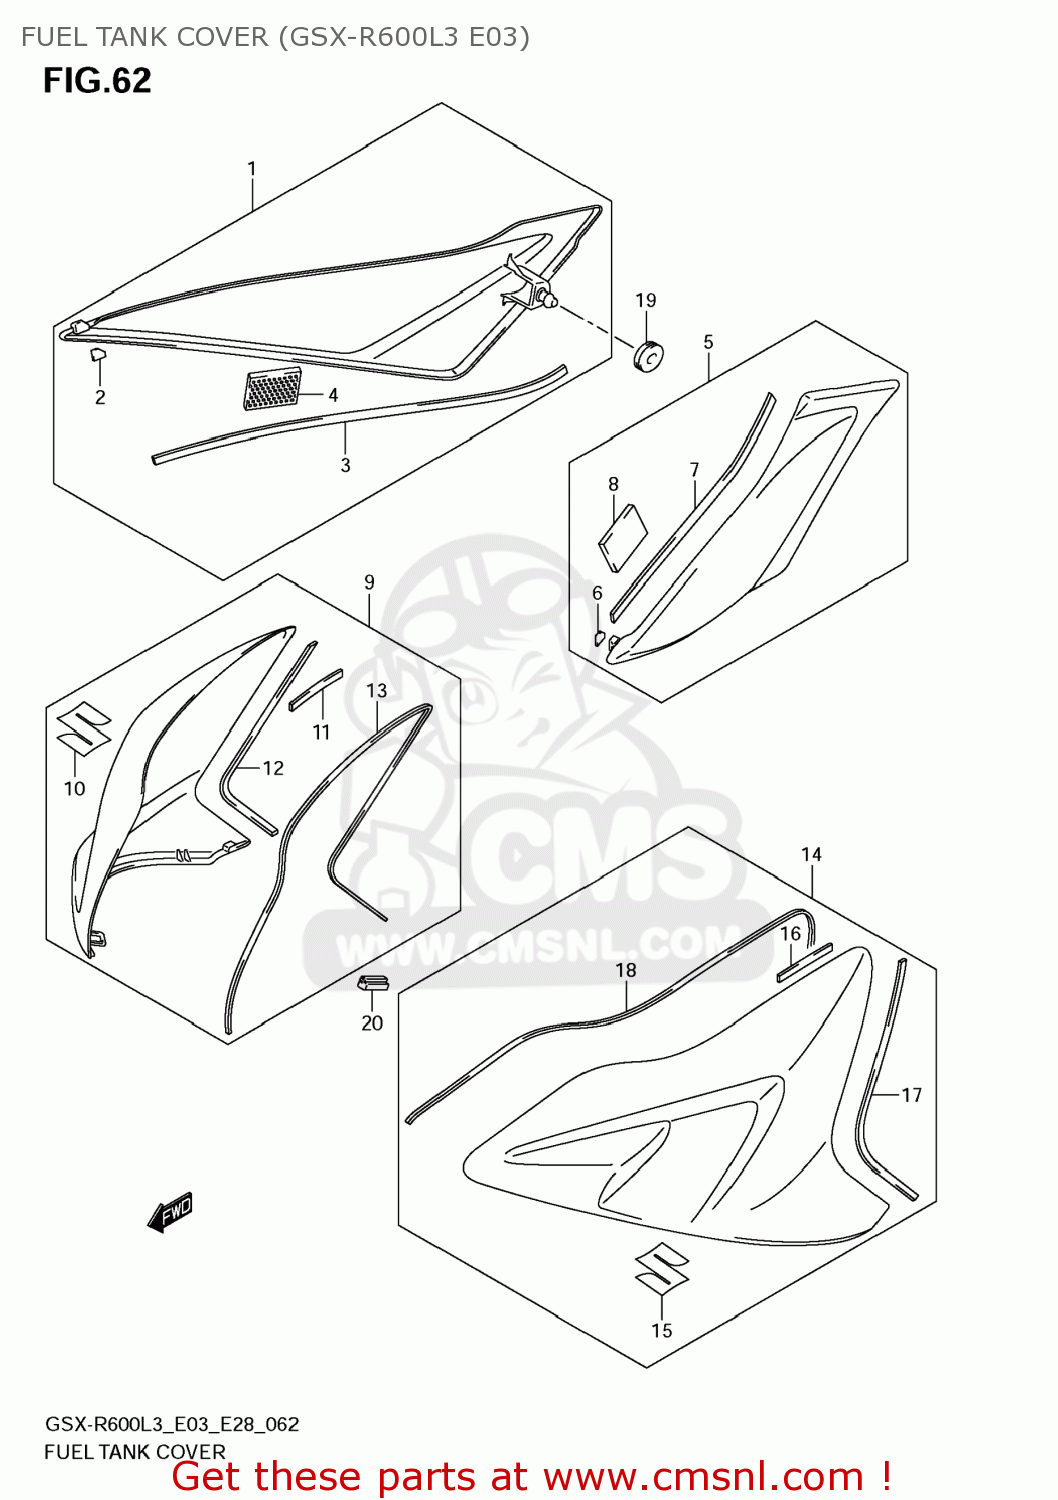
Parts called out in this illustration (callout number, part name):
1	COVER,FUEL TANK SIDE,R
2	CUSHION,FUEL TANK COVER
3	CUSHION,FUEL TANK SIDE COVER
4	FASTENER
5	COVER,FUEL TANK SIDE,L
6	CUSHION,FUEL TANK COVER
7	CUSHION,FUEL TANK SIDE COVER
8	FASTENER
9	COVER,FUEL TANK FR,R
10	EMBLEM,S
11	CUSHION,FUEL TANK COVER NO.1
12	CUSHION,FUEL TANK COVER,R NO.2
13	CUSHION,FUEL TANK COVER FR
14	COVER,FUEL TANK FR,R
15	EMBLEM,S
16	CUSHION,FUEL TANK COVER NO.1
17	CUSHION,FUEL TANK COVER,L NO.2
18	CUSHION,FUEL TANK COVER FR
19	CUSHION,FUEL TANK COVER SIDE
20	CUSHION,FUEL TANK COVER FR
